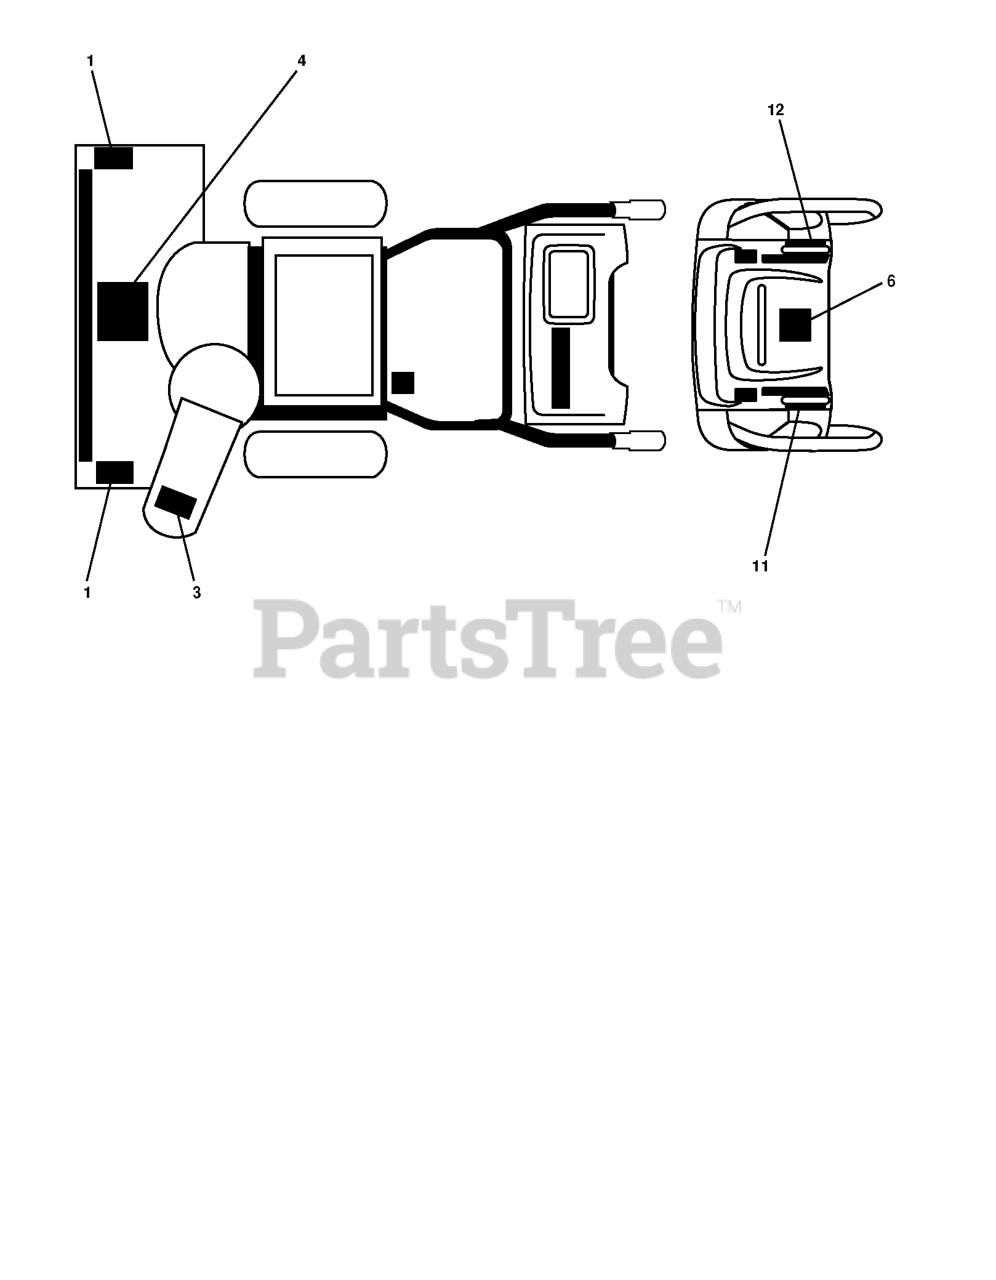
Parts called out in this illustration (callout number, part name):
1	DECAL.SNOWTHR.AUGER
3	DECAL.SNOWTHR.CHUTE.SAFETY
4	DECAL.SNOWTR.READ.OWN.MAN.E/F
6	DECAL, INSTRUCTION
9	DECAL SPEED CONTROL
11	DECAL.TRACT/CLUTCH.LEV.LH.E/F
12	DECAL.AUGER.LEVER.RT.E/F
